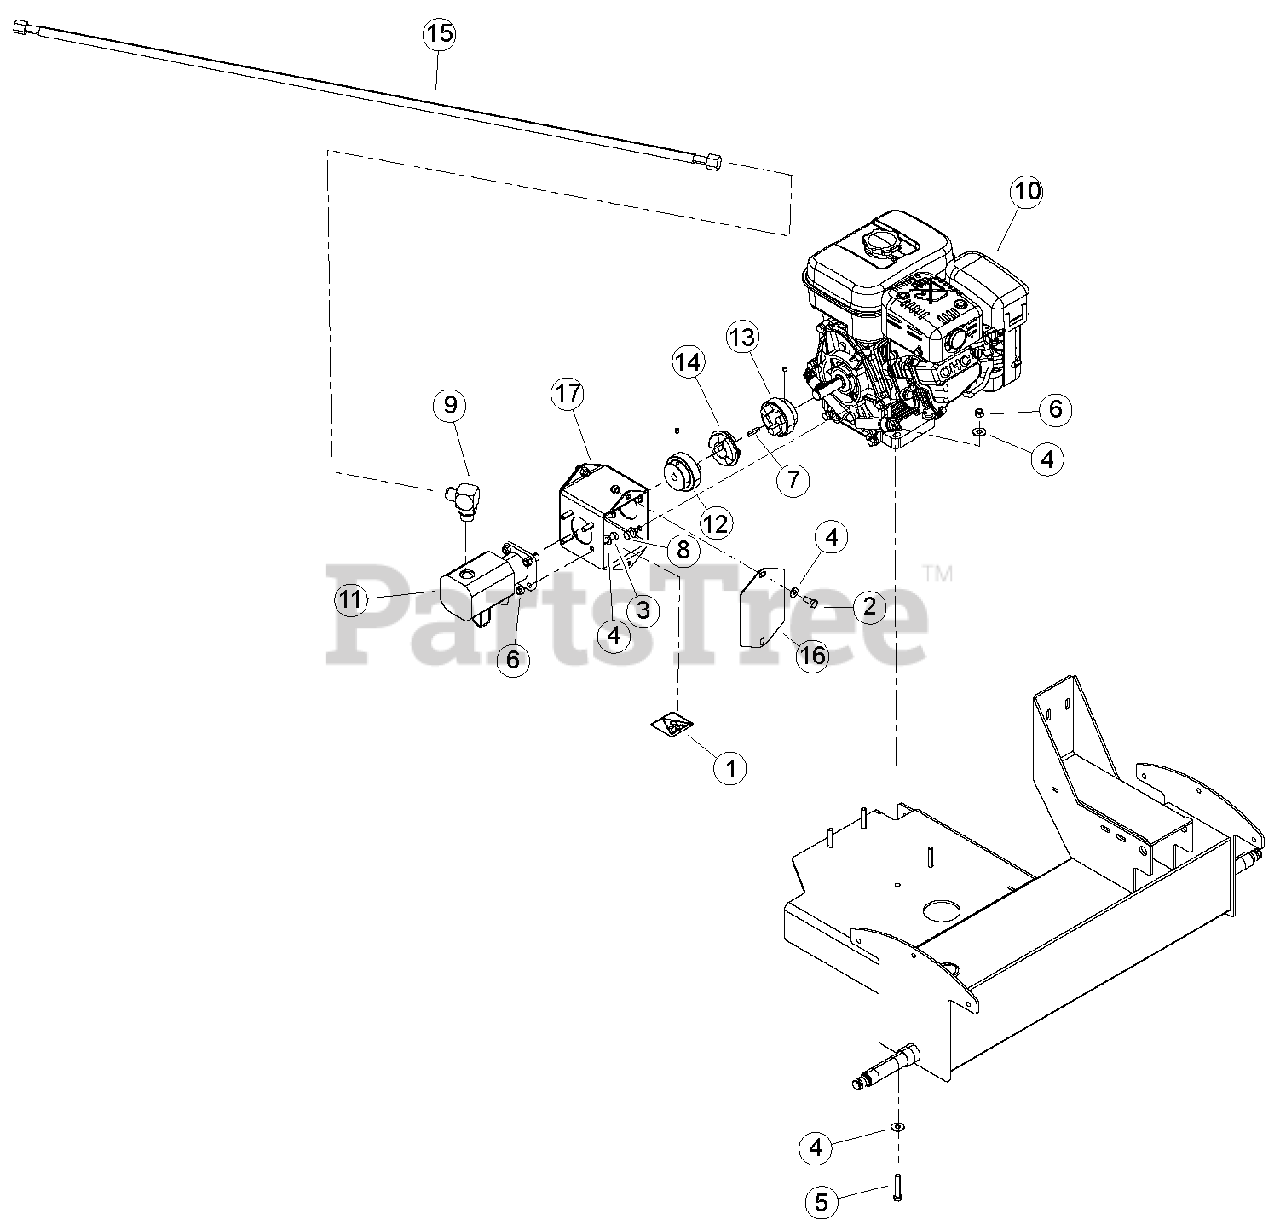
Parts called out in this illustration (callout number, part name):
1	DECAL, SHIELD DANGER ISO
2	BOLT, 5/16 X 3/4 HEX GR5 ZP
3	BOLT, 5/16 X 1 HEX GR5 NC ZP
4	WASHER, 5/16 SAE FLAT
5	BOLT, 5/16 X 1-1/2 HEX GR5 ZP
6	NUT, 5/16 NE NYLOCK ZP
7	SQUARE KEY, 3/16 X 1 LONG
8	BOLT, 5/16-24 X 3/4 HEX GR5 NF ZP
9	ADAPTER, -10 MORING / -10 MJIC 90 DEG.
10	ENGINE, SUBARU 170CC SP170 (FOR SERVICE CONSULT ENGINE OWNER'S MANUAL OR YOUR NEAREST AUTHORIZED SUBARU INDUSTRIAL ENGINE DEALER.)
11	PUMP, LOG SPLITTER 2 STAGE 90 DEG
12	COUPLER, 1/2" ID FLEX DRIVE COUPLING
13	COUPLER, 3/4" ID FLEX DRIVE COUPLING
14	COUPLER, NEOPRENE INSERT FLEX DRIVE COUPLING
15	HOSE, .50 X 50 -10 FJICSW / -10 FJICSW4
16	PLATE, PUMP MOUNT COVER
17	ASSEMBLY, PUMP MOUNT, SERVICE PART
